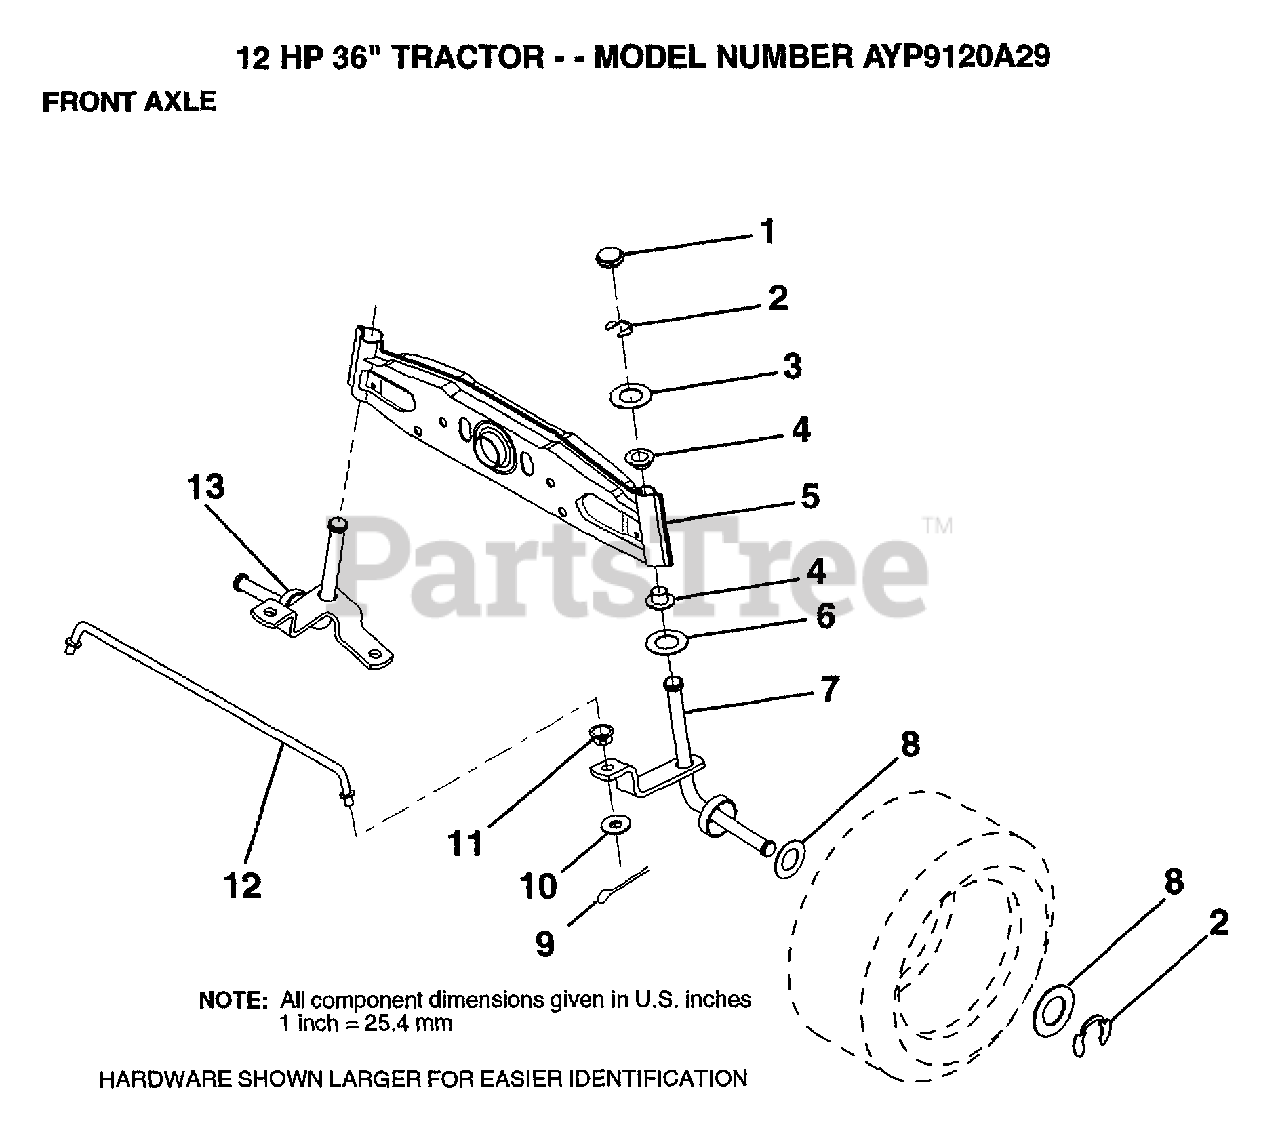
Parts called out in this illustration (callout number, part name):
1	CAP
2	RING
3	WASHER
4	NYLINER
5	AXLE FRONT
6	WASHER .T
7	SPINDLE RH
8	WASHER
9	COTTER PIN
10	WASHER
11	BUSHING.DRAGLINK
12	ROD TIE
13	SPINDLE LH
